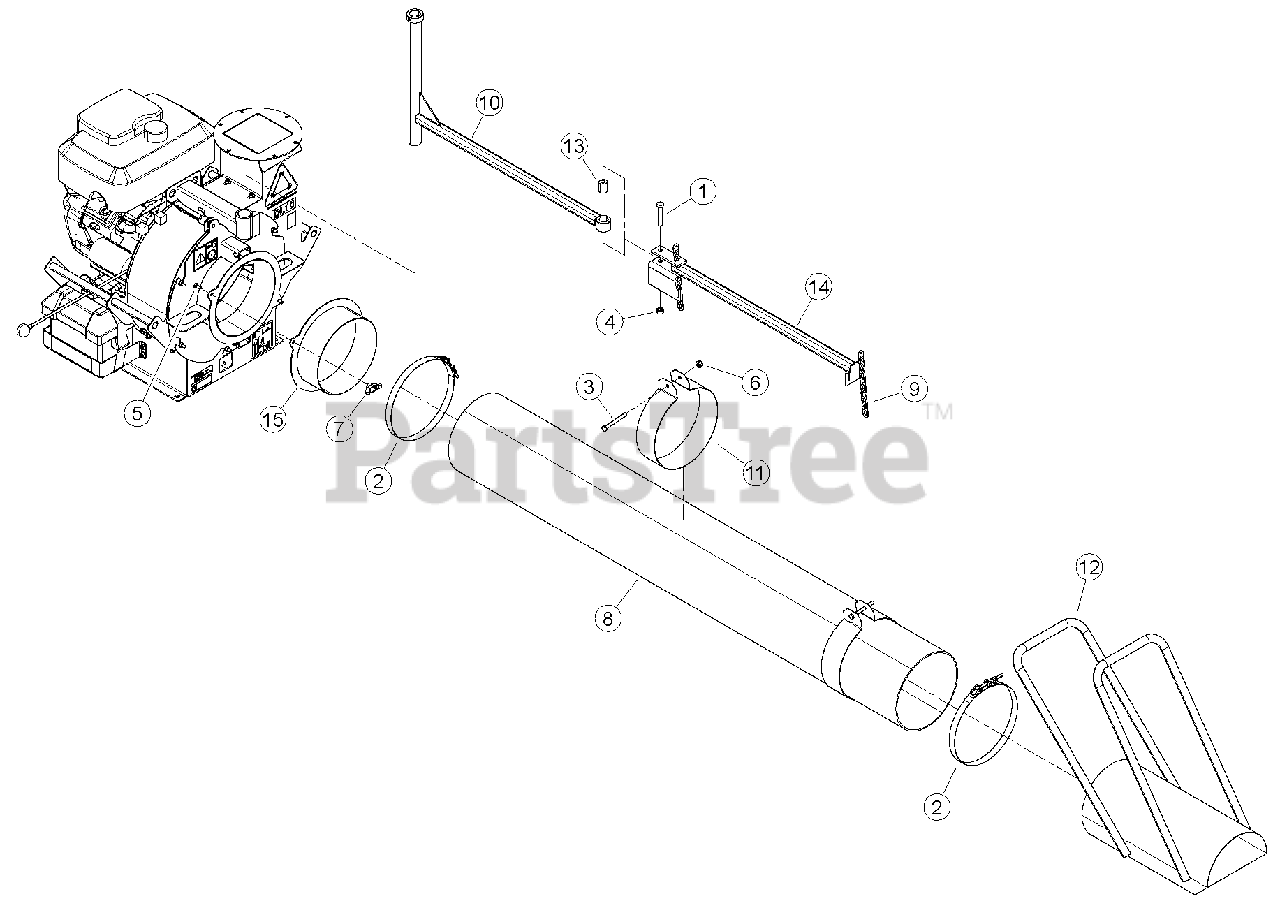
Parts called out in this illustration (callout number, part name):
1	BOLT, 1/2 X 2-3/4 HEX GR5 ZP
2	CLAMP, 10.50" T-BOLT HOSE
3	BOLT, 3/8 X 3-1/2" HEXHD GR5 ZP
4	NUT, 1/2-13 GR5 CENTERLOCK GRB
5	BOLT, 5/16 X 3/4 GR5 NC ZP CRG
6	NUT, 3/8-16 NYLOCK FLANGE
7	KNOB, 5/16-18 UNC TEE W/ LOCKING INSERT
8	HOSE, 10 INCH X 12-1/2 FT
9	CHAIN, HOSE SUPPORT
10	WELDMENT, HOSE SUPPORT
11	WRAP, HOSE SUPPORT
12	WELDMENT, HOSE INLET 10 INCH
13	SPACER, 1.00 OD X 0.25 X 1.26
14	WELDMENT, HOSE SUPPORT
15	WELDMENT, INLET ADAPTER
